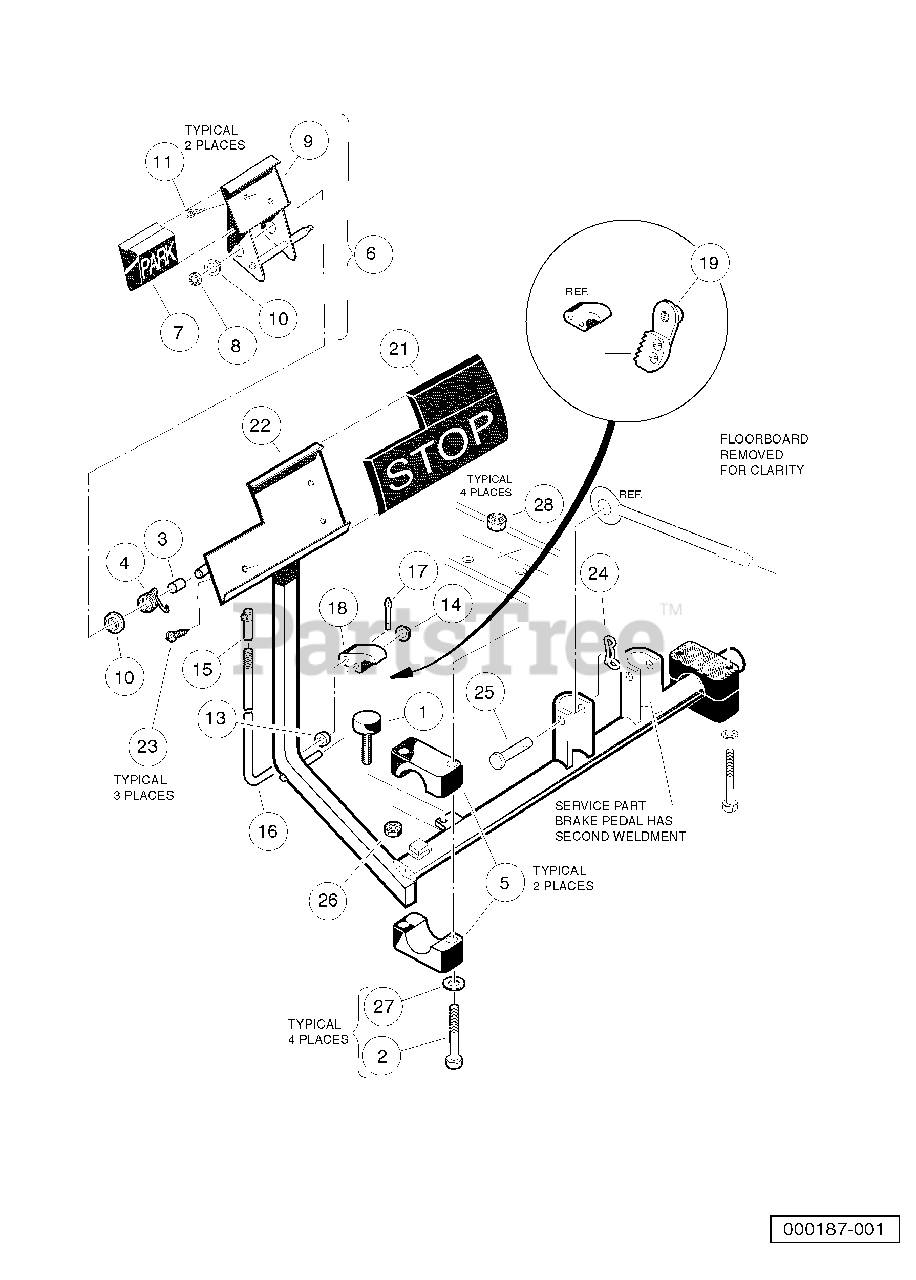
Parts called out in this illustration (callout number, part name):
1	Bumper, Rubber
2	Screw, 5/16-18 X 2.50 Hex Cap
3	Hill Brake Spacer
4	Spring, Hill Brake Torsion
5	Package, Brake Mounting Block
6	Kit, Hill Brake Pedal
7	Pad, Hill Brake
8	Pushnut, 3/8
9	Hill Brake Weld Assembly
10	Bushing, Nylon
11	Screw, #10-16 Type AB, Sheet Metal
12	Kit, Hill Brake Latch
13	Sleeve, Hill Brake Rod
14	Pushnut, 3/8
15	Ball Joint, 1/4-28
16	Rod, Hill Brake
17	Pin, Cotter, 7/64 x 1/2 Stainless-Steel
18	Pawl, Hill Brake
19	Ratchet Assembly
20	Brake Pedal Kit
21	Pad, Brake Pedal
22	Weldment, Brake Pedal 4wb Std
23	Screw, #10-16 Type AB, Sheet Metal
24	Pin, Bow Tie Locking
25	Pin, 3/8 X 1-5/16 Clevis
26	Nut, 1/4-20 Hex
27	Washer, 5/16 Type A Flat
28	Locknut, 5/16-18 Nylon Insert
